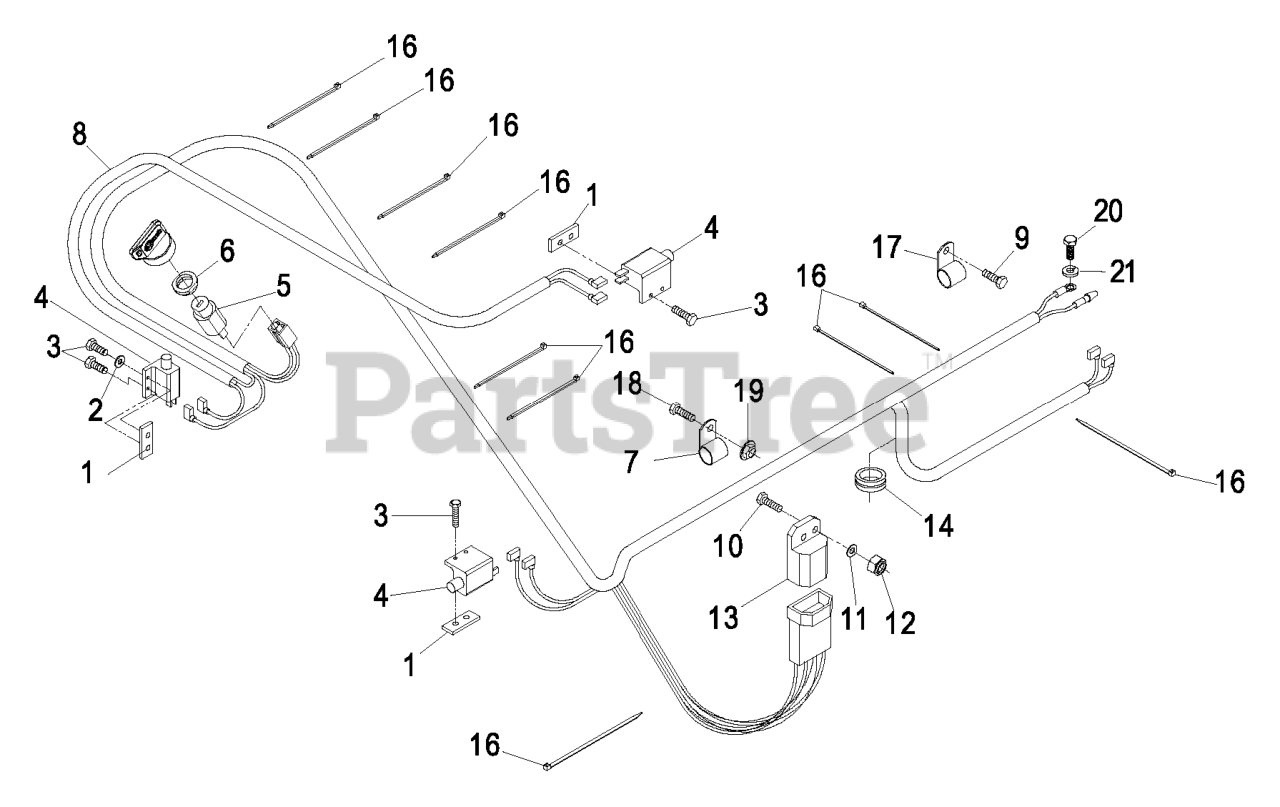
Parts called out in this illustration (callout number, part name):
1	PLATE-TAPPED
2	WASHER-FLAT
3	SCREW-PPH
4	SWITCH-OPEN, NORMALLY
5	SWITCH & KEY (INCLUDES NU
6	NUT-SWITCH, IGNITION
7	CLIP-LOOM
8	HARNESS-WIRING
9	SCREW-HH
10	SCREW-HH
11	WASHER-FLAT
12	NUT-LOCK, NI
13	MODULE-INTERLOCK
14	GROMMET
16	TIE-CABLE
17	CLIP-LOOM
18	SCREW-HH
20	SCREW-HH
21	WASHER-LOCK
